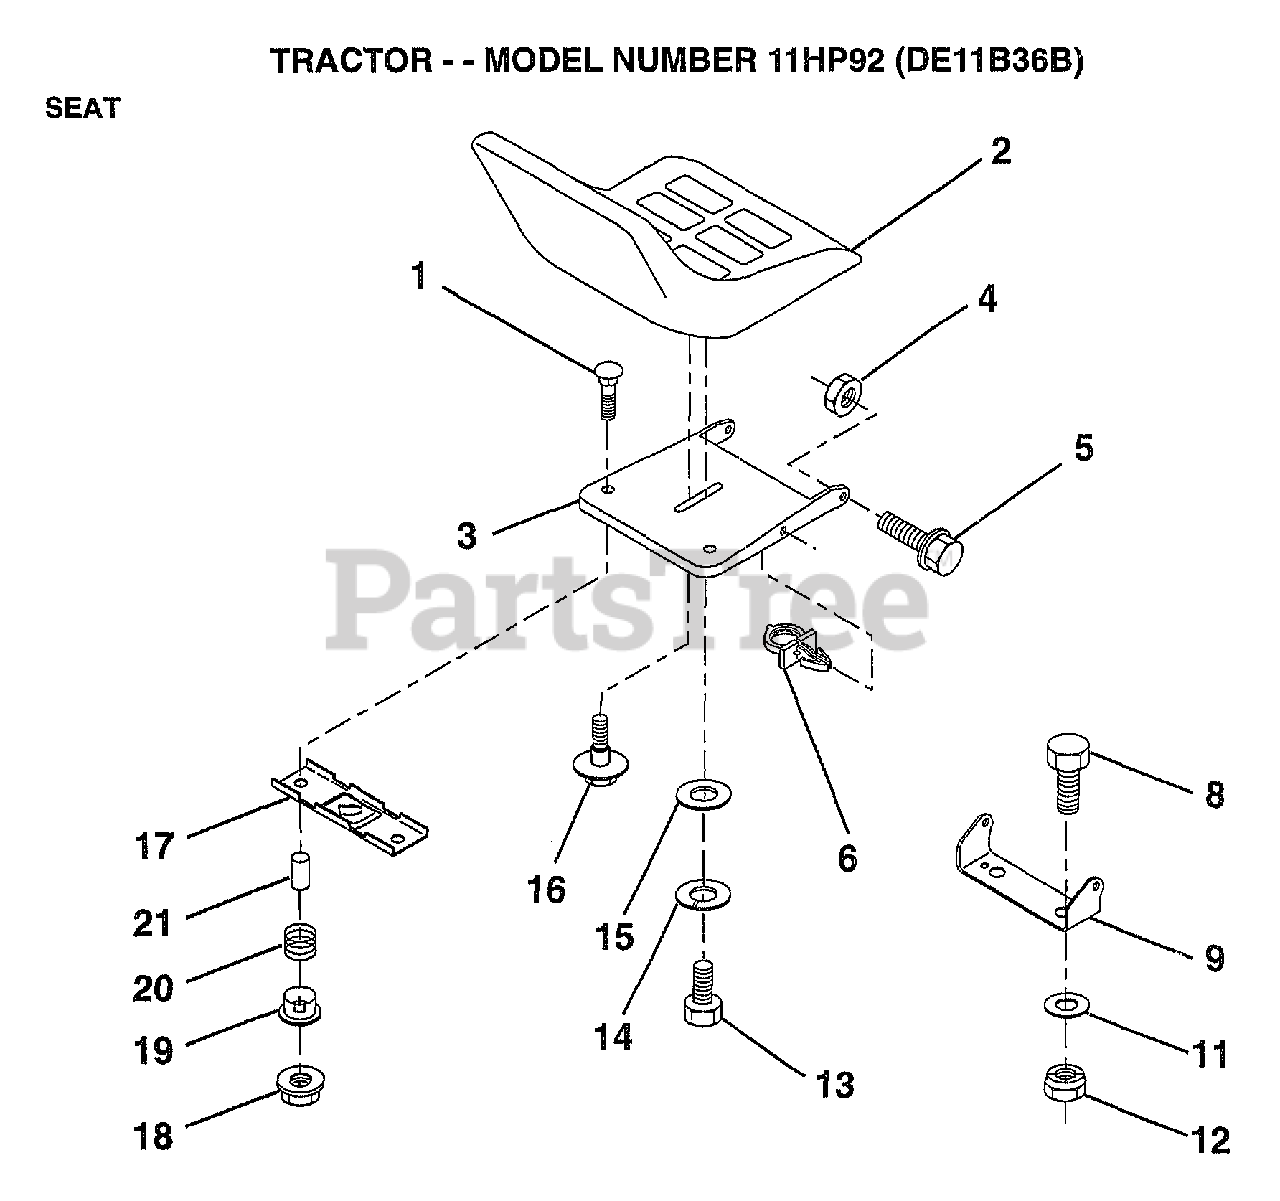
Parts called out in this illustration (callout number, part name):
1	BOLT-RD HD SQ NK
3	PAN-SEAT
4	NUT
5	"BOLT,SHOULDER"
6	CLIP.PUSH-IN.HING
8	BOLT
9	BRACKET PVT SEAT
11	WASHER
12	NUT
13	BOLT
14	LOCKWASHER
15	WASHER
16	"BOLT,SHOULDER"
17	BRKT SWITCH
19	BUSHING
20	SPRING
21	SPLIT SPACER
